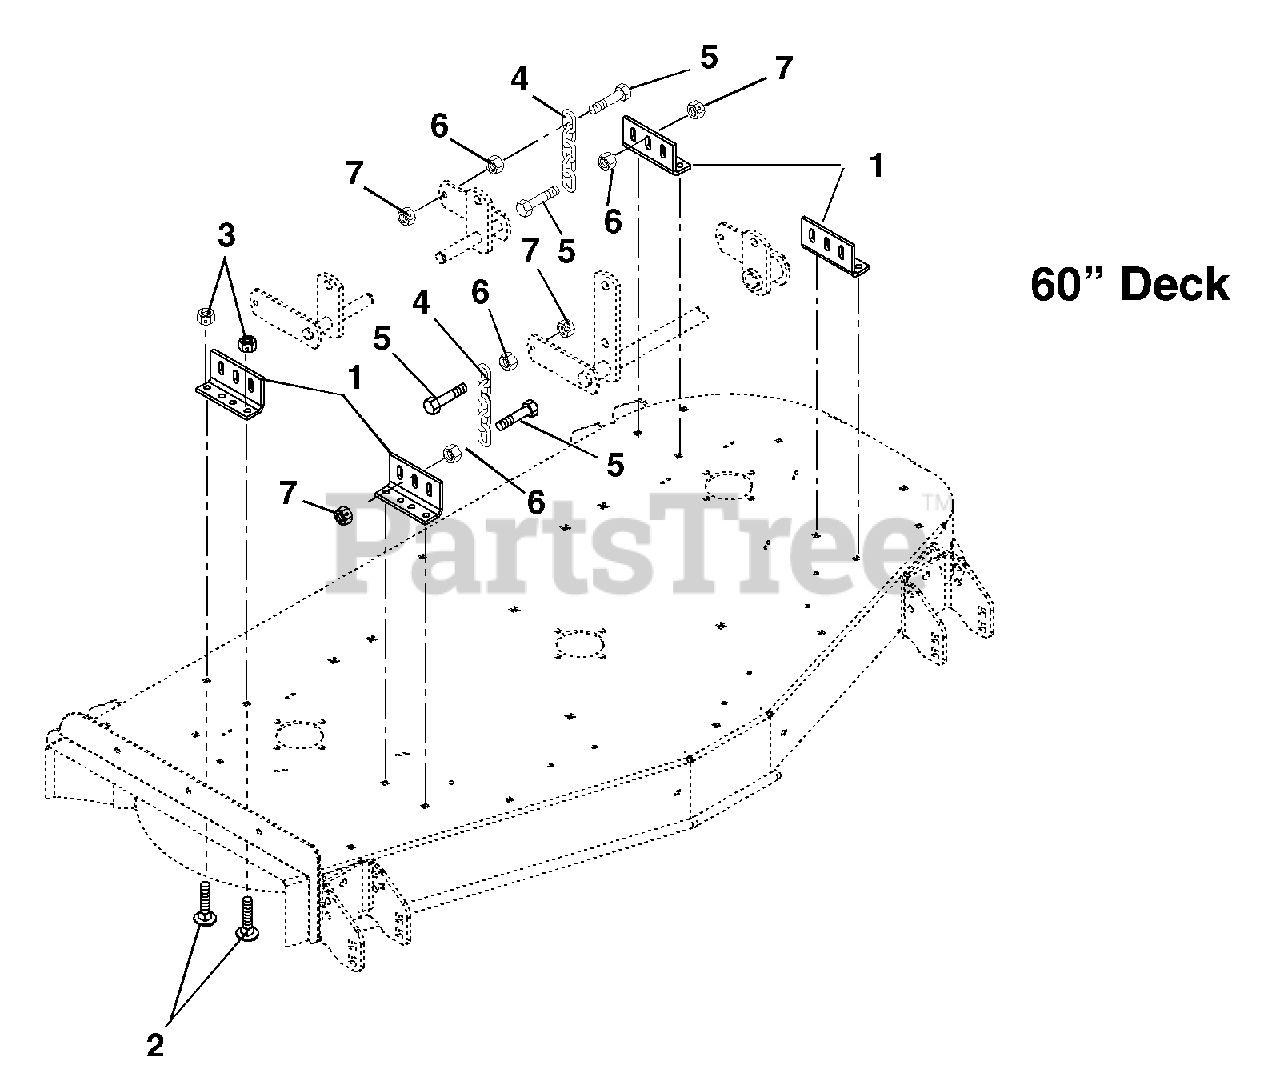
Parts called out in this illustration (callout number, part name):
1	MOWER MOUNTING BRACKET - RED
2	@BLT-RDHDSQNK .38-16X1.00 G5YZ
3	@NUT-LK-TOP-FLG .38-16 YWZC
4	CHAIN, LINK
5	@BLT-HEX .50-13X2.00 GR5 YWZC
6	NUT-SPNLK-FLG .50-13 YWZC
7	@NUT-LK-TOP-FLG .50-13 YWZC
